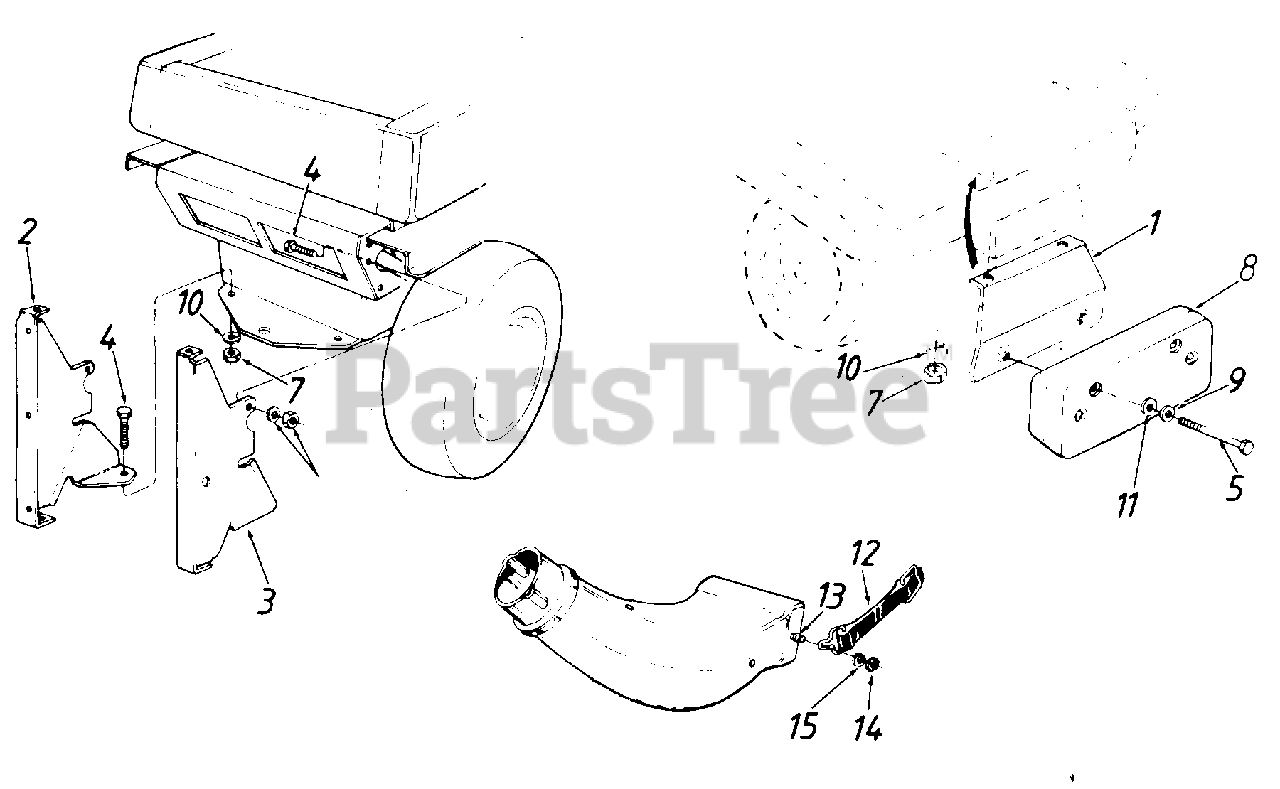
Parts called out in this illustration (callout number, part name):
1	Counterweight Support Brkt.
2	Catcher Support Brkt.-R.H.
3	Catcher Support Brkt.-L.H.
4	Hex Cap Bolt 5/16-18 x 1.0" Lg.
5	Hex Bolt 3/8-16 x 4.5" Lg.
7	Hex Nut 5/16-18 Thd.*
8	Front Counterweight
9	Bell.-Wash. 3/8" I.D.
10	L.-Wash 5/16" I.D.*
11	Fl.-Wash. .390" I.D. x 1.12" O.D.
12	Mounting Strap
13	Hex Bolt 1/4-20 x 5/8" Lg.*
14	Hex Nut 1/4-20 Thd.*
15	Spr. Wash. .267 I.D. x .562" O.D.
